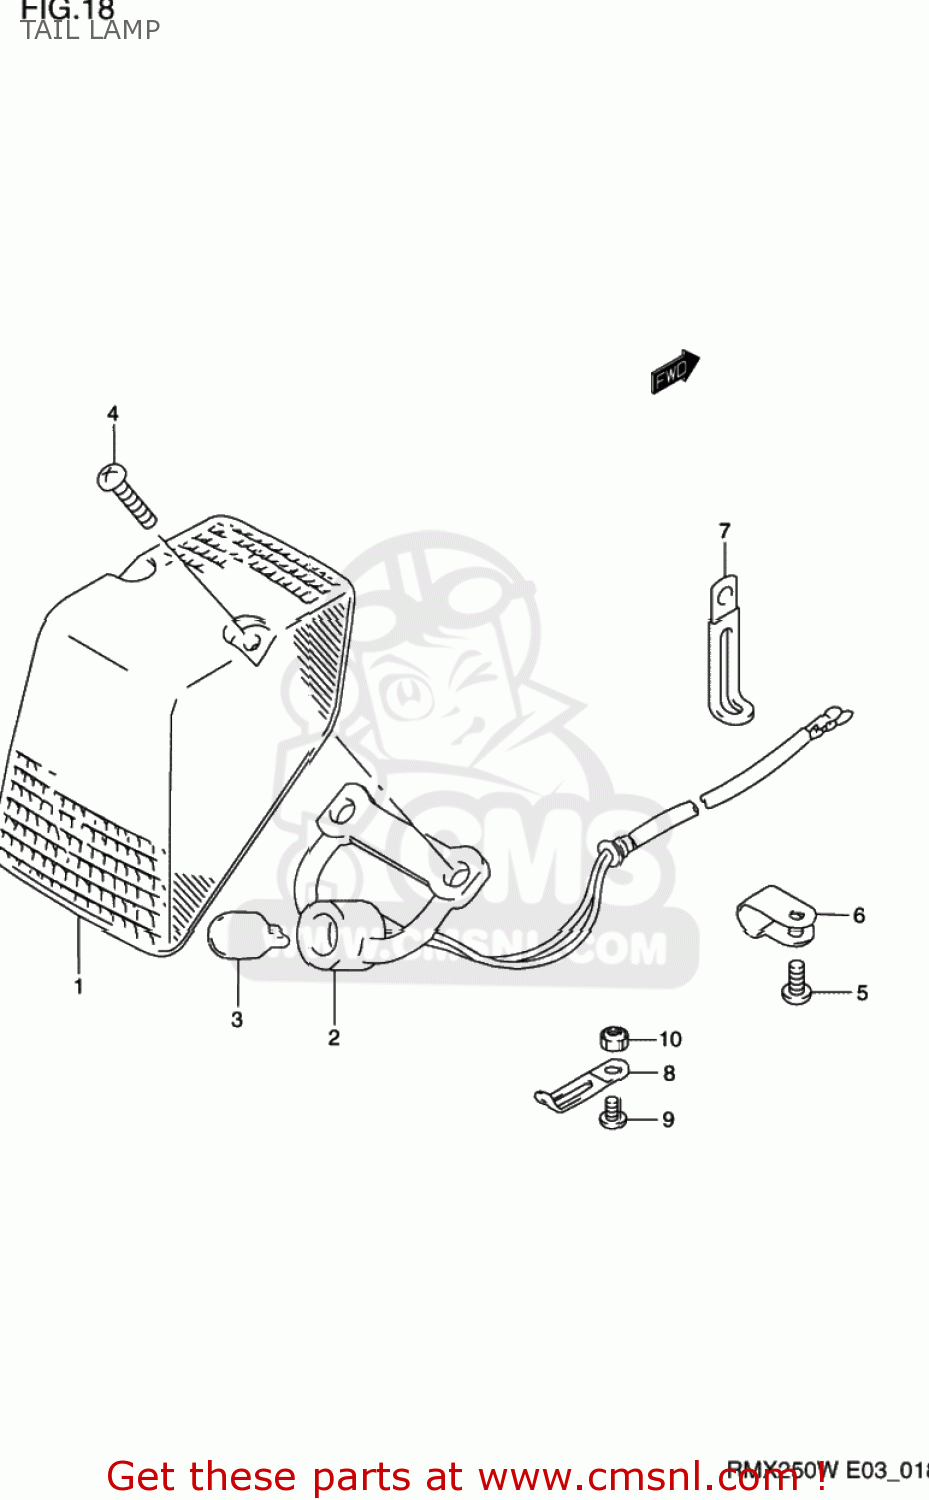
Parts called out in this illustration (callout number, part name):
1	LENS
2	SOCKET & CORD,RR COMBINATION
3	BULB(12V5W)
4	SCREW
5	SCREW, TRUNK BOX
6	CLAMP
7	CLAMP L:62
8	CLAMP(L:45)
9	SCREW 6X10
10	NUT 6MM
